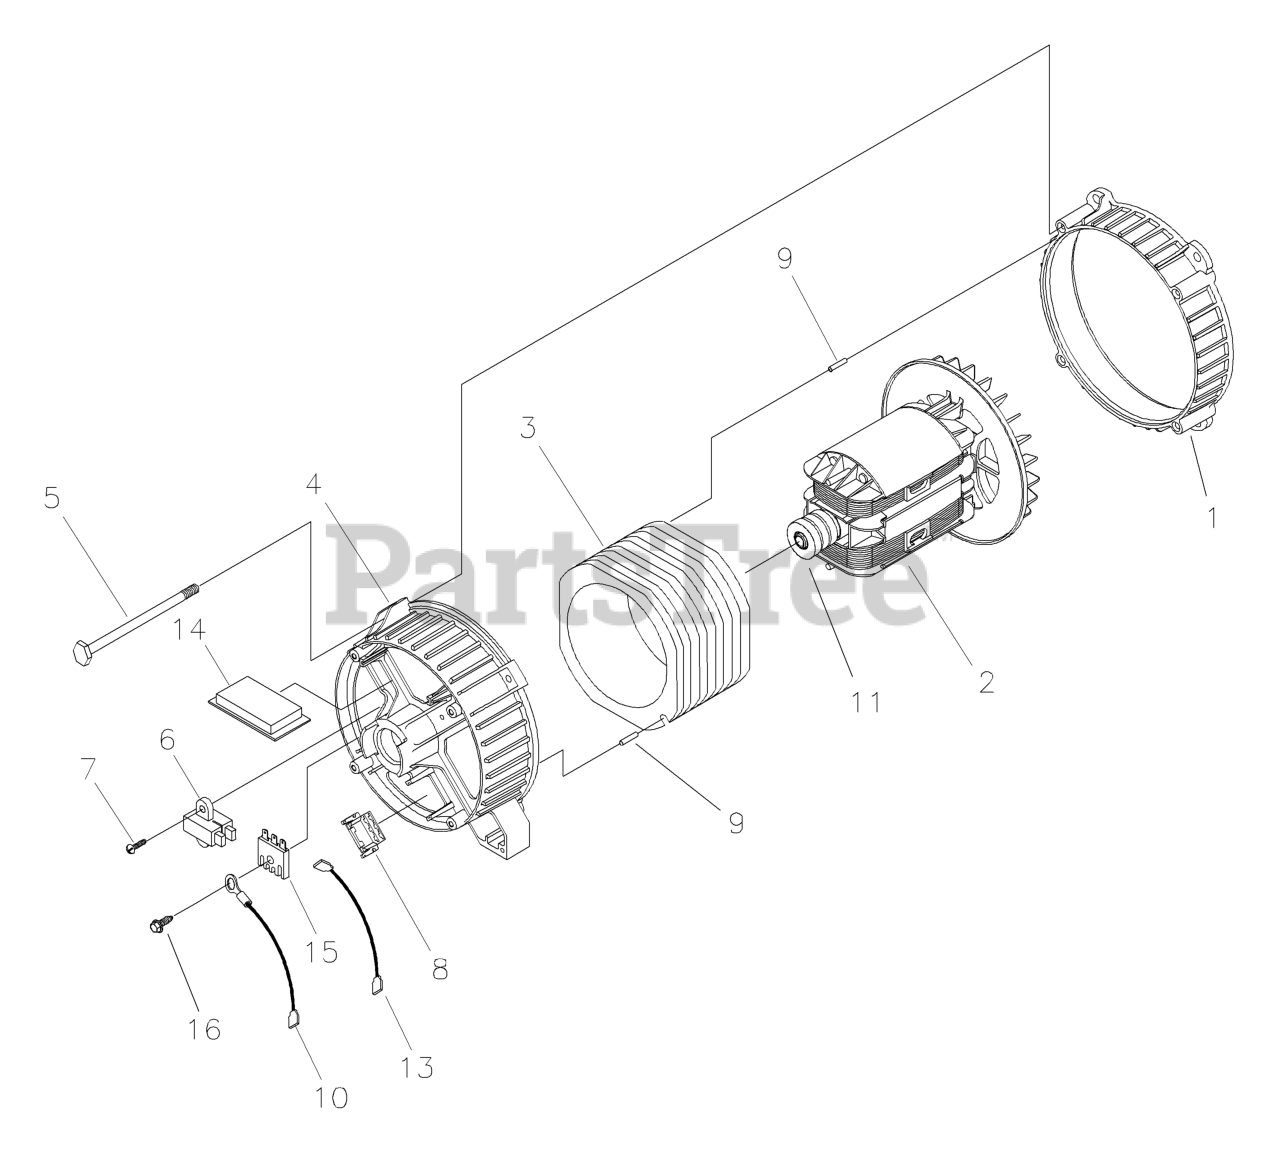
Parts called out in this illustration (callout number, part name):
1	ADAPTER, Mounting,Alternator
2	ROTOR
4	RBC
5	HHCS, M6 - 1.0 x 140 SEMS
6	ASSY, Holder, Brush
7	TAPTITE, M5 - 0.8 x 16
8	RECEPTACLE, 6 pin
9	PIN, Roll, 4mm x 10
10	ASSY,Wire, Ground
13	ASSY,Wire, Ground
14	REGULATOR,Voltage,AVR
15	RECTIFIER
16	TAPTITE, M5 - 0.8 x 20
